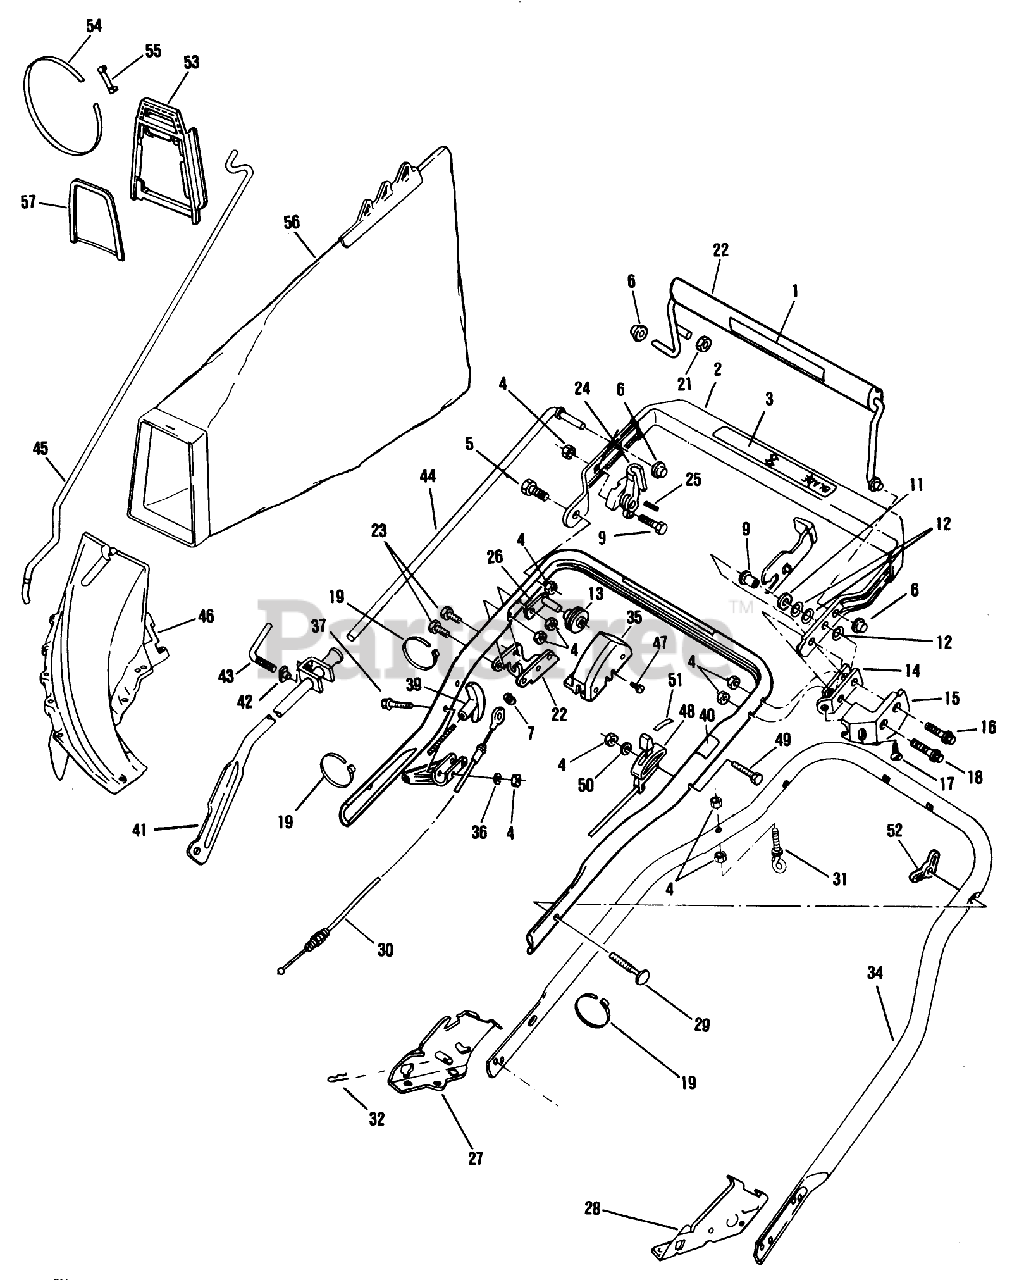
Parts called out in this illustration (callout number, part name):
4	LOCKNUT E
5	BOLT
7	RET. RING
9	SPACER
11	WASHER M
13	PULLEY PL
14	DOWN STOP
15	LOCKOUT GUARD
16	BOLT SHOU
17	SCREW F
18	SCREW
21	NUT ACORN
24	CAM HOFFER
27	BRACKET ASM - HANDLE, SP, RH
28	BRACKET ASM - HANDLE, SP, LH
29	BOLT QUALITY
30	CONTROL CABLE
31	EYE BOLT WAS MFG
32	HAIR PIN
36	WASHER
39	HANDLE START UM&D
41	CONTROL LEVER AY
44	CONTROL ROD
45	ROD GRASSBAG
47	7011 21 LB MOWER O/
50	WASHER-FLAT
53	CHUTE - ADAPTER
56	ORD 89816 WHOLE GOODS
57	CHUTE BRACE
S2	NUT-WING
